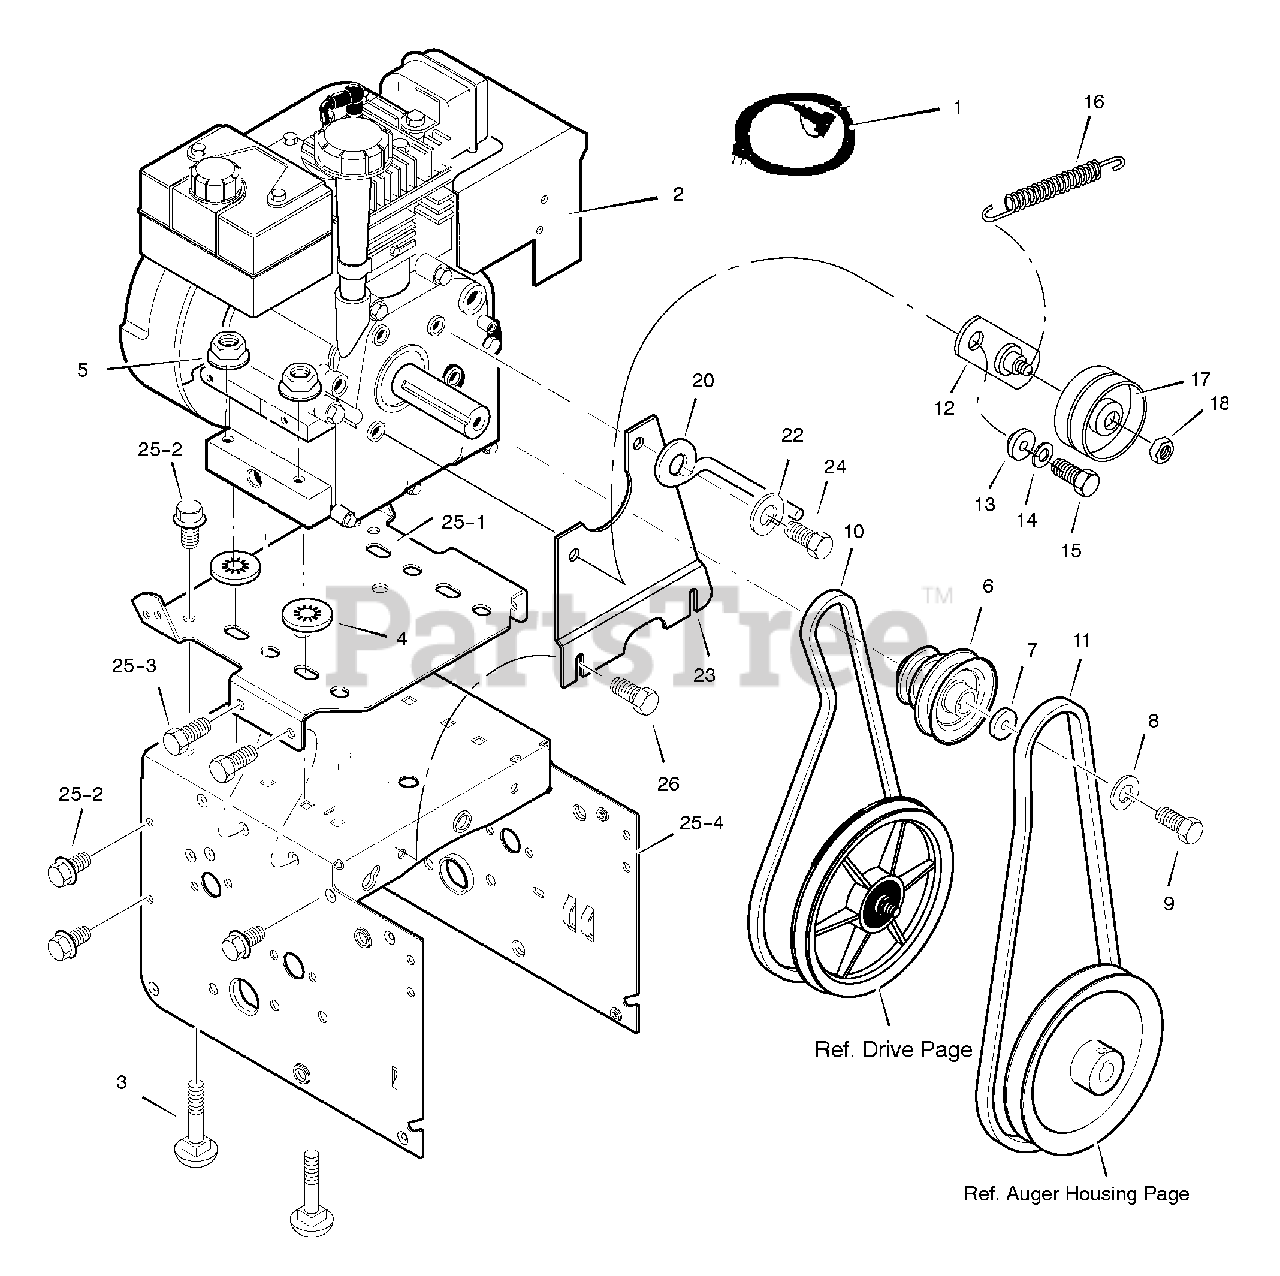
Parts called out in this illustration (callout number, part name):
1	CORD, Electric, 10FT. 110V
2	ENGINE
3	BOLT, CARRIAGE 5/16-18
4	RETAINER, PUSH
5	NUT, HEX 5/16-18
6	PULLEY, ENGINE
8	WASHER .38ID
9	SCREW, 3/8-24 x 1.00
10	BELT, DRIVE V 3L
11	BELT, AUGER V 4L
12	BRACKET ASSEMBLY, IDLER
13	BUSHING, IDLER BRACKET
14	WASHER, SPLIT
15	SCREW 5/16-24 X 1.00
16	SPRING, IDLER TRACTION DRIVE
17	PULLEY, IDLER
18	NUT, JAM 3/8-16
20	GUIDE, BELT
22	WASHER, SPTLK .31X.58X.08
23	PLATE, ANTI VIBRATION
24	SCREW, 5/16-24 x 1.00
25	FRAME ASSEMBLY
25-1	PLATE, ENGINE MOUNT
25-2	SCREW, TAP 1/4-20 X .63
25-3	SCREW, TAP 5/16-18 X .50
25-4	FRAME, MOTOR BOX
